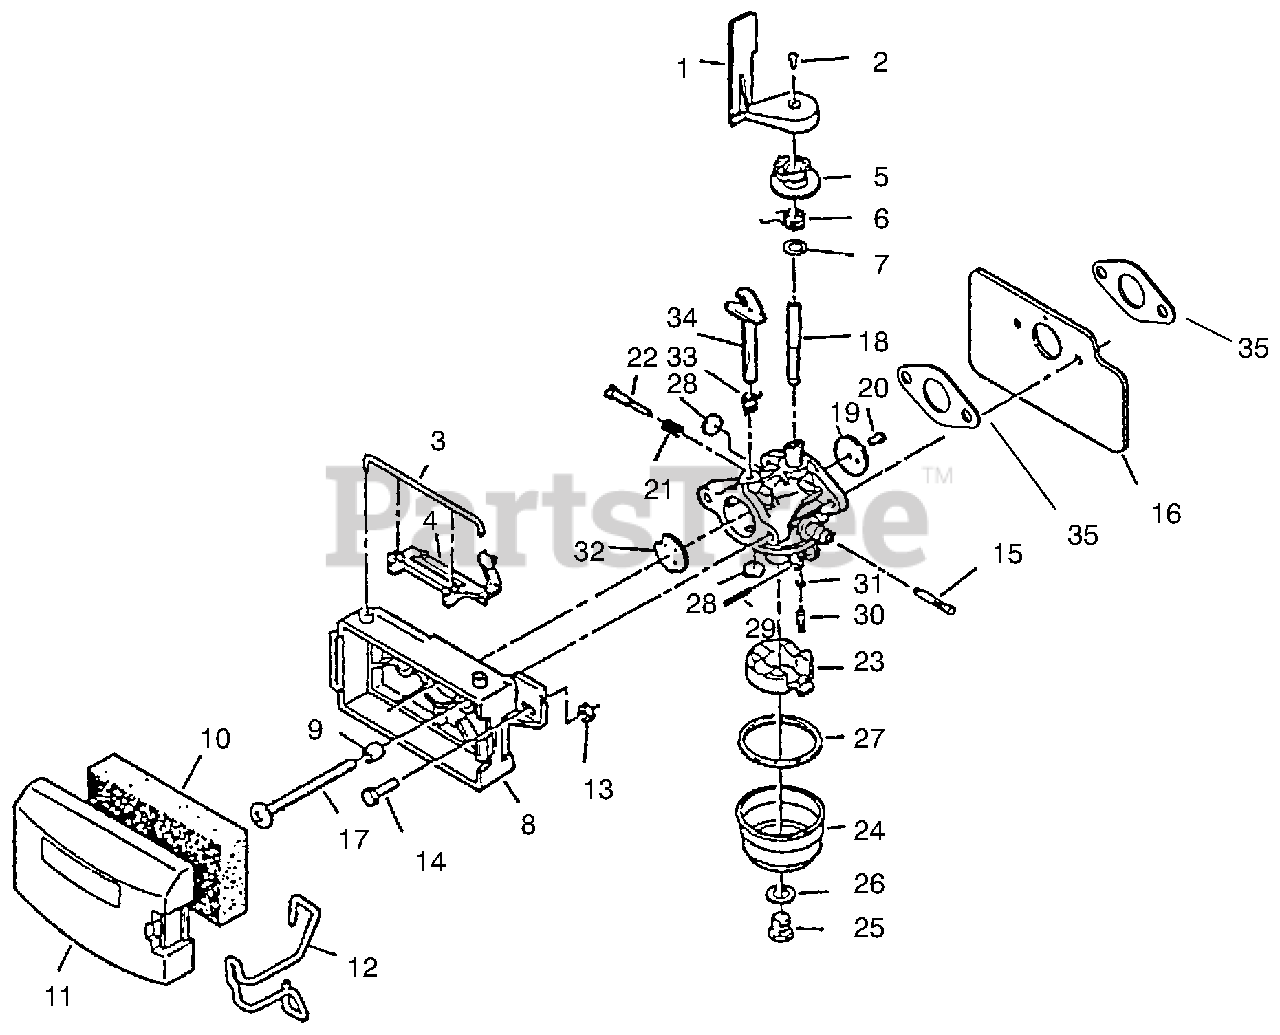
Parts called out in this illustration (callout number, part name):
1	Vane-Air
3	Retainer-Speed Control Lever
4	Lever-Governor Control
8	Base-Air Filter
9	Spacer-Filter Base
10	Element-Air Filter
11	Cover-Air Filter
12	Retainer-Cover
13	Nut
15	Filter-Fuel
16	Shield-Heat
18	Shaft-Throttle
19	Vane-Throttle
20	Screw
21	Spring-Needle
22	Needle-Idle
23	Kit-Float Assembly
24	Bowl-Fuel
25	Screw
26	Gasket-Bowl Retainer
27	Gasket-Bowl
28	Plug-Welch
29	Shaft-Float
30	Inlet-Needle Valve
31	Seat-Valve
32	Valve-Choke
33	Spring-Return
34	Shaft-Choke
35	Gasket Carburetor
